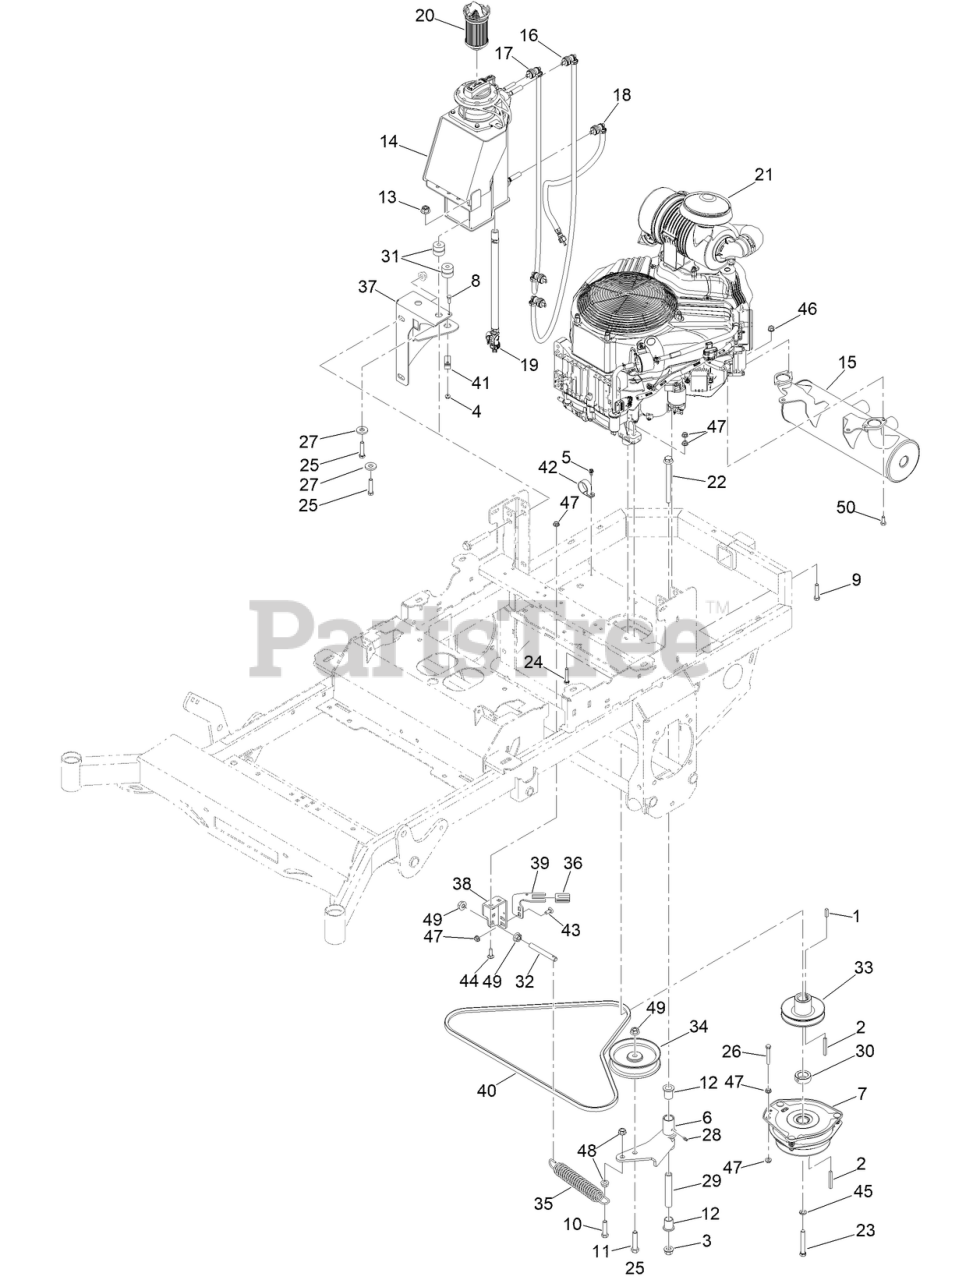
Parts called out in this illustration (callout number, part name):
3	NUT-LOCK
4	NUT-HF
5	SCREW-HWH
6	KGZ PUMP IDLER PULLEY ARM ASSEMBLY
7	KGZ-XD OGURA CLUTCH 3600 RPM
8	SCREW-HH
9	SCREW-HH
10	SCREW-HH
11	SCREW-HH
12	3/4IN ID X15/16IN OD X 1-1/8IN FLNG BUSH
13	3/8-16 NYLON INSERT FLANGE L/NUT YZ
14	VANGUARD OIL GUARD TANK
15	DUAL EXH SYSTEM W/MUFF BIG BLOCK ENGN
16	OIL HOSE ASSY SUPPLY
17	OIL HOSE ASSY SCAVENGE
18	OIL HOSE ASSY VENT
19	OIL FLEX DRAIN HOSE
20	OIL FILTER FOR OIL GUARD
21	VANGUARD 40HP EFI WITH OIL GUARD
22	1/2-13 X 5-1/2 HEX FLANGE BOLT GR 8 ZY
23	7/16-20 X 3 HEX C/S GR 8 ZC YELLOW
24	5/16-18 X 1-3/4 HEX C/S GR 5 ZINC YELLOW
25	3/8-16 X 1-3/4 HEX C/S GR 2 ZINC
26	5/16-18 X 2-1/4 HEX C/S (GR.2) ZC YELLOW
27	1/2 FENDER WASHER 1-1/4IN OD ZINC
28	1/4IN DRIVE TYPE GREASE FITTING YZ
29	MWR INNER IDLER SPACER
30	KGZ-XD PUMP DRIVE PULLEY SPACER
31	OIL GUARD ISOLATOR
32	MWR PUMP IDLER SPRING TENSIONER
33	MWR HYDRAULIC PUMP DRIVE PULLEY (B-BELT)
34	5-3/4IN IDLER PULLEY 7/16IN SPACER ASSY
35	MWR DECK SPRING
36	SPARTAN QUICK SHIELD ROD GUIDE BUSHING
37	MWR OIL GUARD TANK BRKT BLACK
38	MWR PUMP IDLER TENSIONING BRKT BLACK
39	KGZ OGURA CLUTCH BRKT PAINTED
40	MWR PUMP BELT XD B X 69.40IN EFF LNGTH
41	1-1/4IN CUSHIONED LOOP CLAMP BLACK
42	3/4 EPDM CUSHION CLAMP
43	BOLT-CARR
44	BOLT-CARR
45	WASHER-LOCK
46	3/8-16 HEX FLANGE NUT W/SERR ZINC YELLOW
48	NUT-HF
49	1/2-13 HEX FLANGE NUT W/SERR ZINC
50	M8-1.25 X 20MM HEX FLANGE BOLT ZINC 10.9
